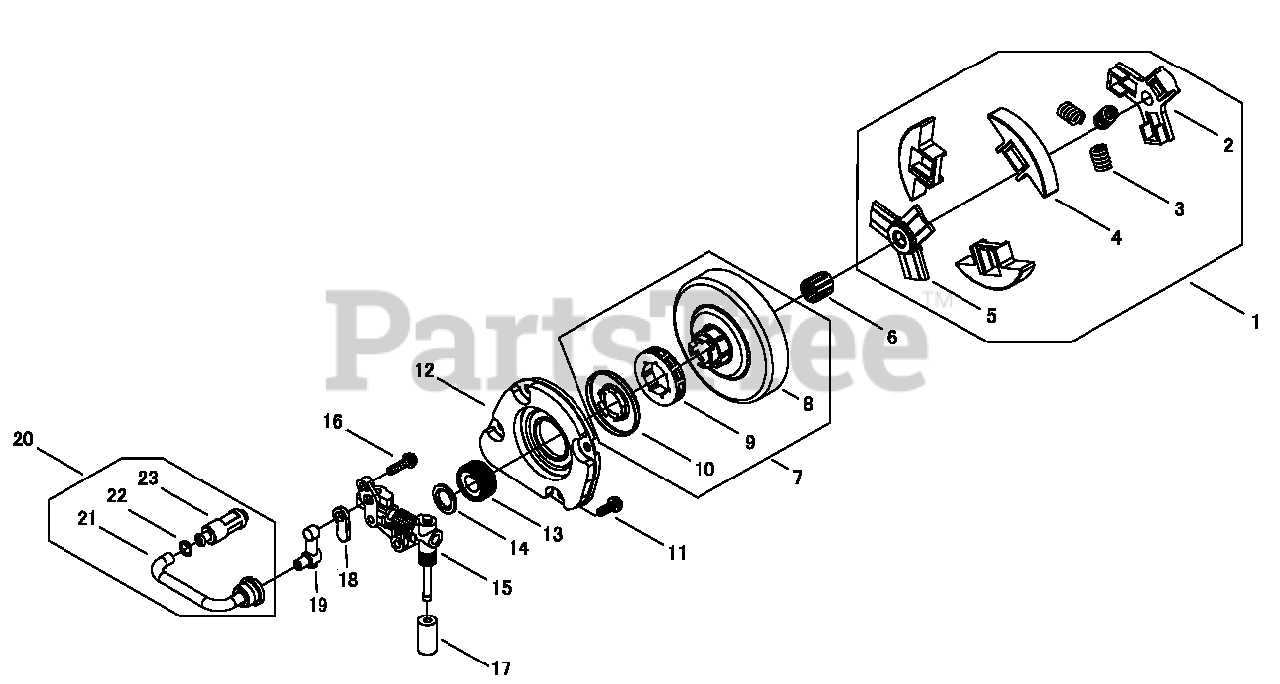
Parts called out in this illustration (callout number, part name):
1	CLUTCH ASSY
2	BOSS, CLUTCH B
3	SPRING, CLUTCH
4	SHOE, CLUTCH
5	BOSS, CLUTCH A
6	BEARING, NEEDLE 10
7	DRUM ASSY, CLUTCH
8	DRUM, CLUTCH
9	SPROCKET, 0.325 RIM
10	COVER
11	SCREW
12	PUMP COVER, FLOCKED
13	GEAR
14	PLATE, THRUST
15	OIL PUMP ASSY
16	SCREW M4×16
17	FILTER
18	GASKET, OIL PUMP
19	ELBOW
20	PIPE ASSY, OIL
21	PIPE, OIL
22	CLIP, OIL FILTER
23	FILTER, OIL
